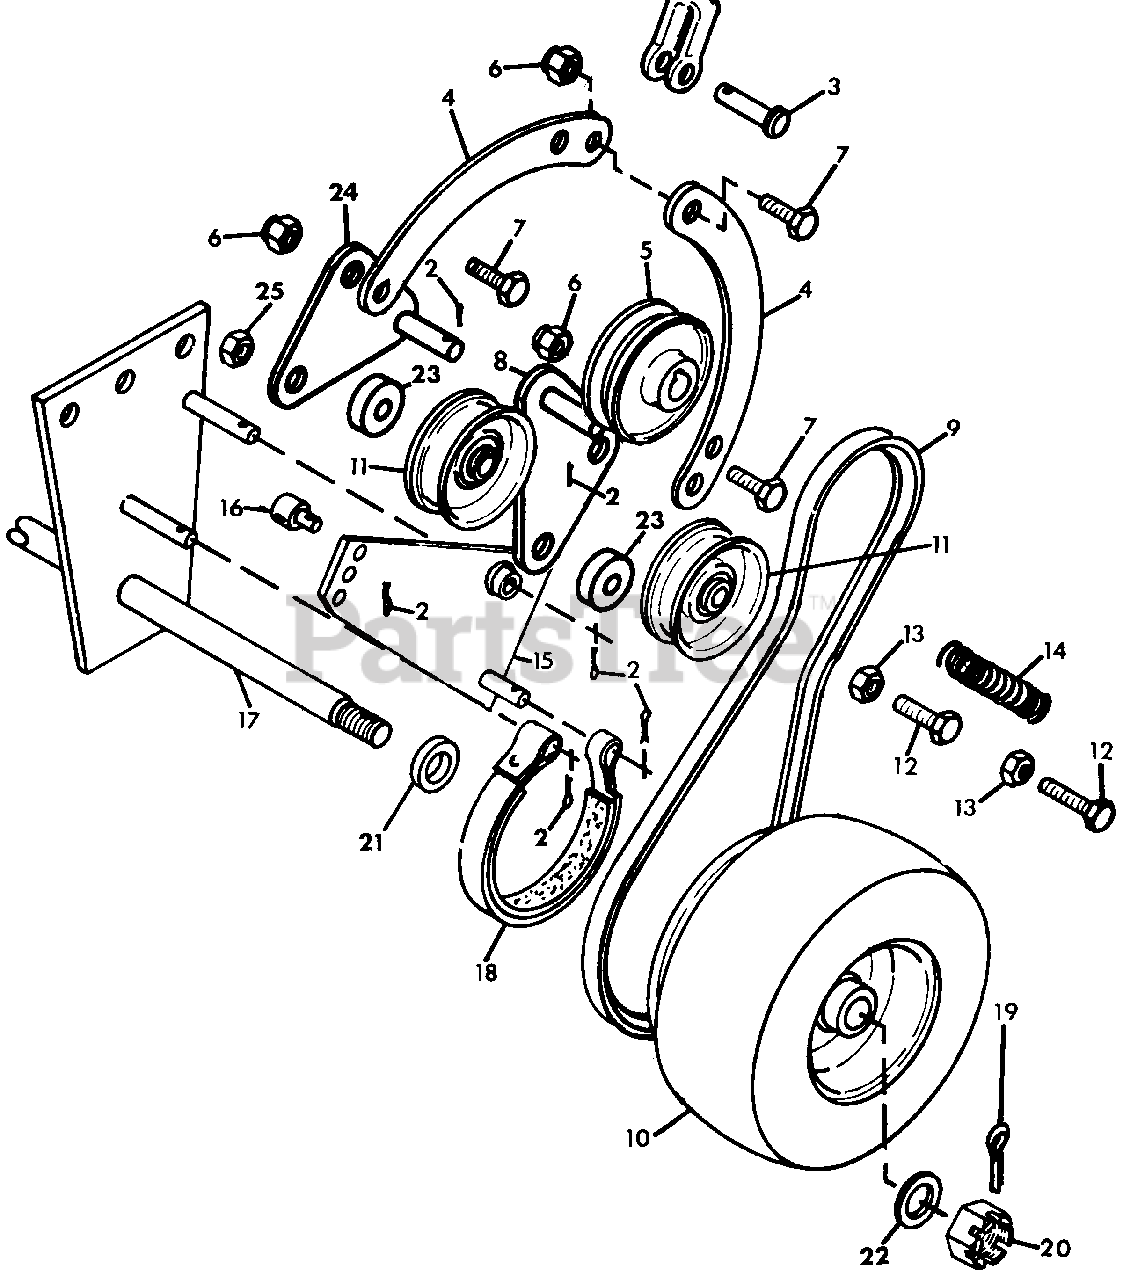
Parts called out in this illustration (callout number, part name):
1	CLEVIS, 5/16
2	PIN, COTTER .09X.625
3	PIN, CLEVIS .312X.812
4	STRAP, WHEEL CLUTCH ACTUATING
5	PULLEY, JACK-SHAFT
6	NUT, LOCK 5/16-18
7	BOLT, HEX 5/16X.625
8	LEVER, WHEEL CLUTCH IDLER
9	BELT, TRACTION
10	ASSEMBLY, WHEEL & TIRE
11	SHEAVE, IDLER
12	BOLT, HEX 3/8-16X2.0
13	NUT, HEX 3/8-16
14	SPRING
15	WELDMENT, BRAKE LEVER L.H.
15	WELDMENT, BRAKE LEVER R.H.
16	PIVOT, BRAKE ROD
17	WELDMENT, AXLE
18	ASSEMBLY, BRAKE BAND L.H.
18	ASSEMBLY, BRAKE BAND R.H.
19	PIN, COTTER .156X1.50
20	NUT, SLOTTED 3/4-16
21	SPACER, WHEEL
22	WASHER, FLAT .812X1.375X.100
23	SPACER, IDLER
24	WELDMENT, WHEEL CLUTCH L.H.
25	NUT, LOCK 3/8-16
